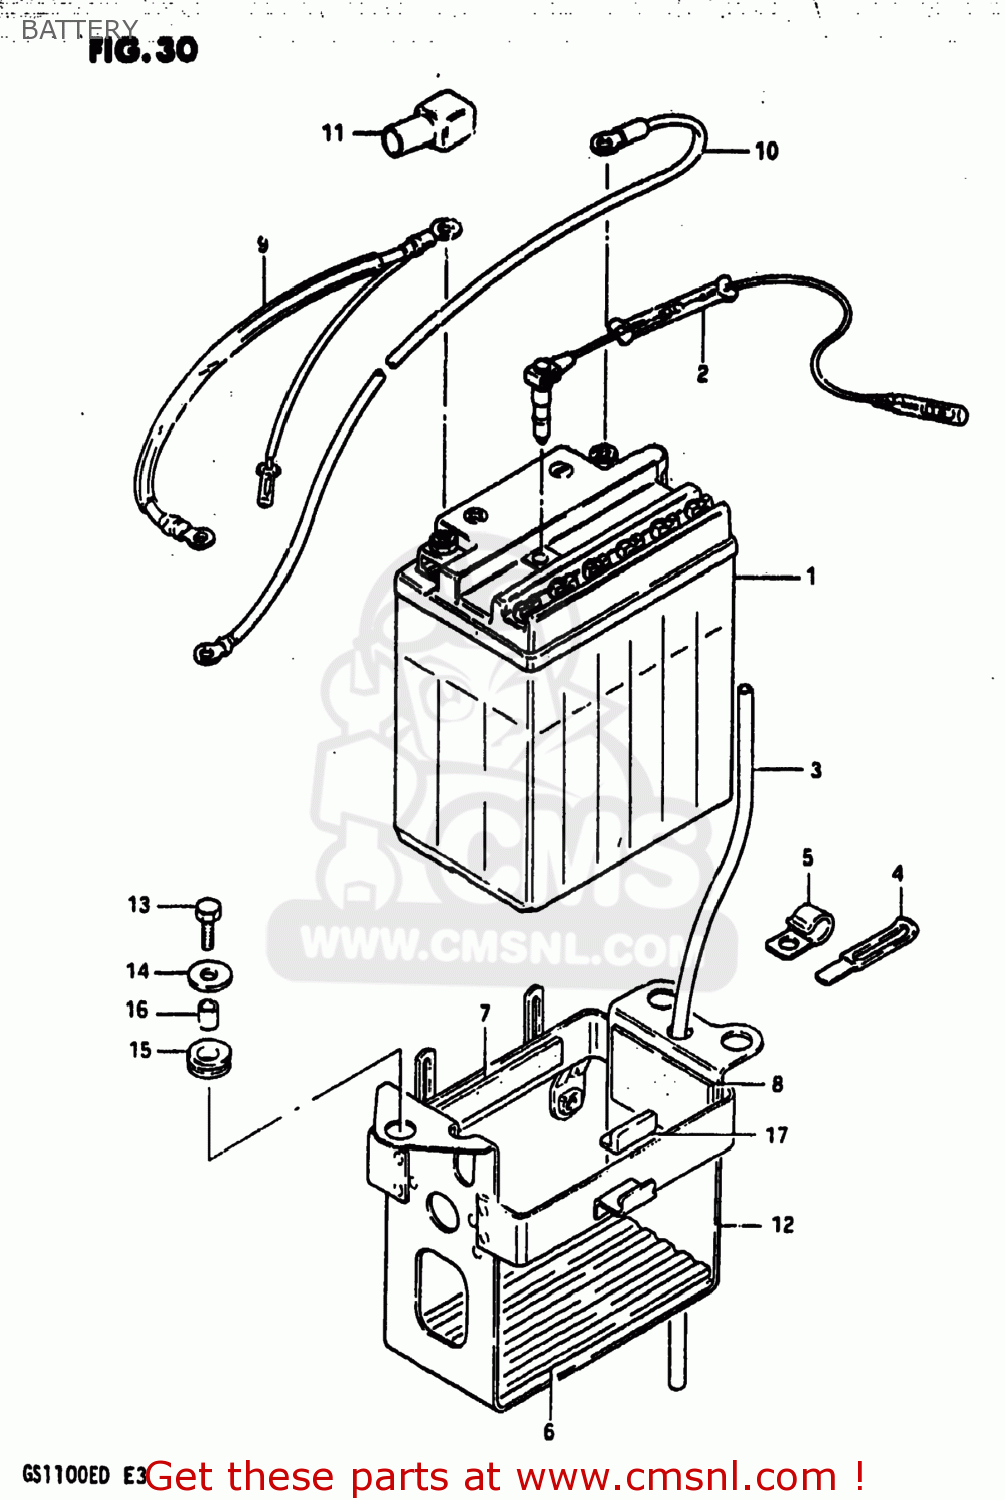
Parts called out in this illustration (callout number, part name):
1	BATTERY ASSEMBLY (12V)
2	SENSOR,BATTERY LEVEL
3	HOSE,BATTERY EXHAUST
4	CLAMP L:35
5	CLAMP
6	PROTECTOR,BATTERY
7	PROTECTOR(20X90)X4
8	PROTECTOR,BATTERY
9	WIRE,BATTERY PLUS
10	LEAD WIRE,BATTERY(-)
11	CAP,TERMINAL
12	HOLDER,BATTERY
13	BOLT, UPPER
14	WASHER
15	CUSHION
16	SPACER(6.1X9X7.5)
17	CUSHION,FRAME COVER
